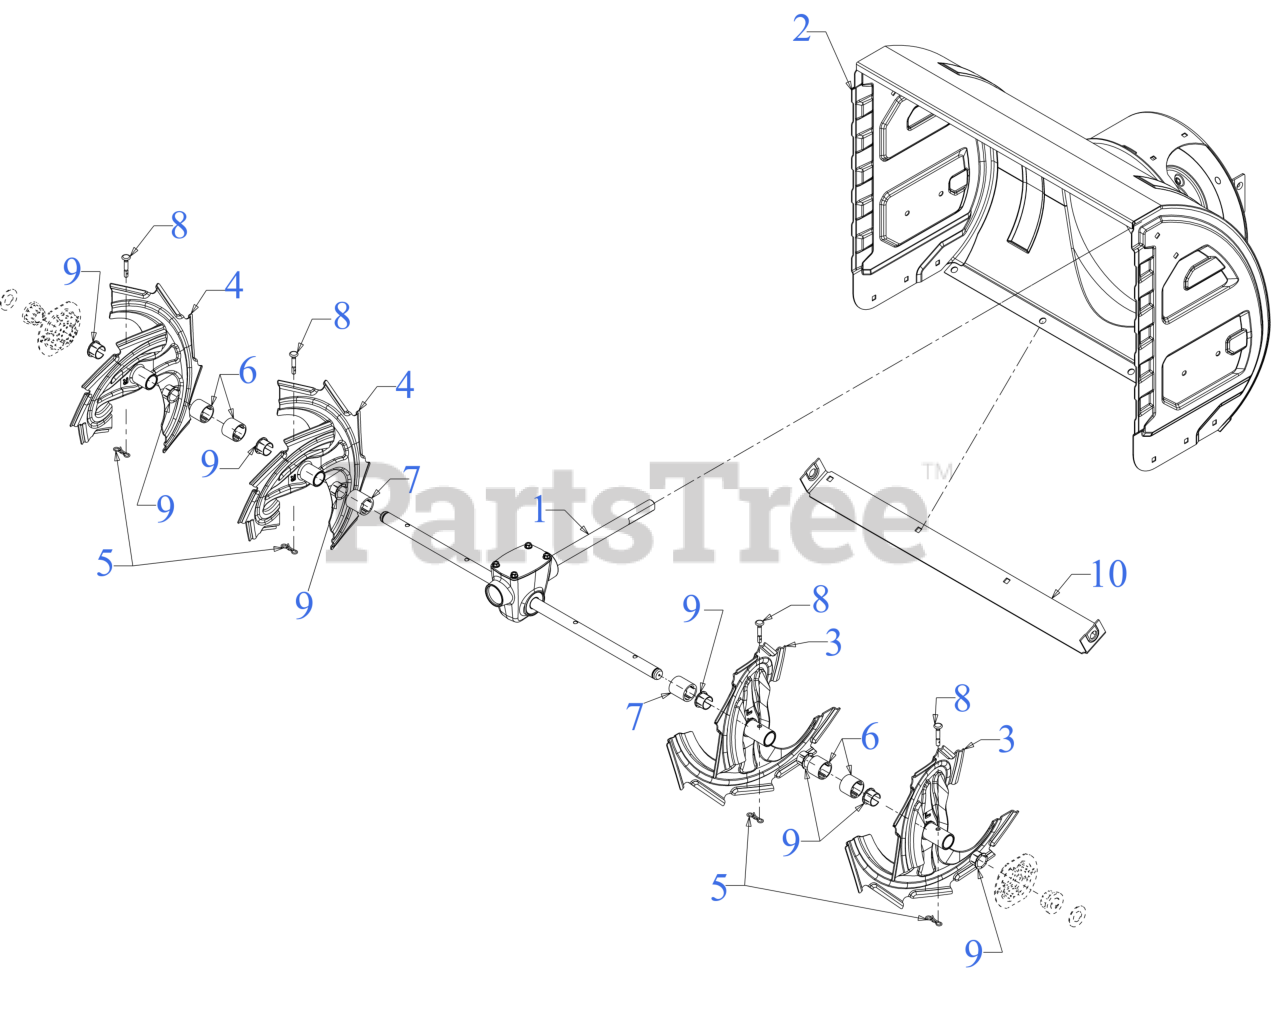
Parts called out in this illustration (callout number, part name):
1	GEARBOX ASSEMBLY 26" 2X HD
3	10T AUGER SPIRAL (LH)
4	10T AUGER SPIRAL (RH)
5	BOW TIE COTTER PIN 1/4-5/16
6	SPACER 1.25OD x .75ID X1.00 LG
7	SPACER 1.25OD x .75ID x 1.312 LG
8	SHEAR PIN .25 x 1.50 GR2
9	FLANGE BUSHING
